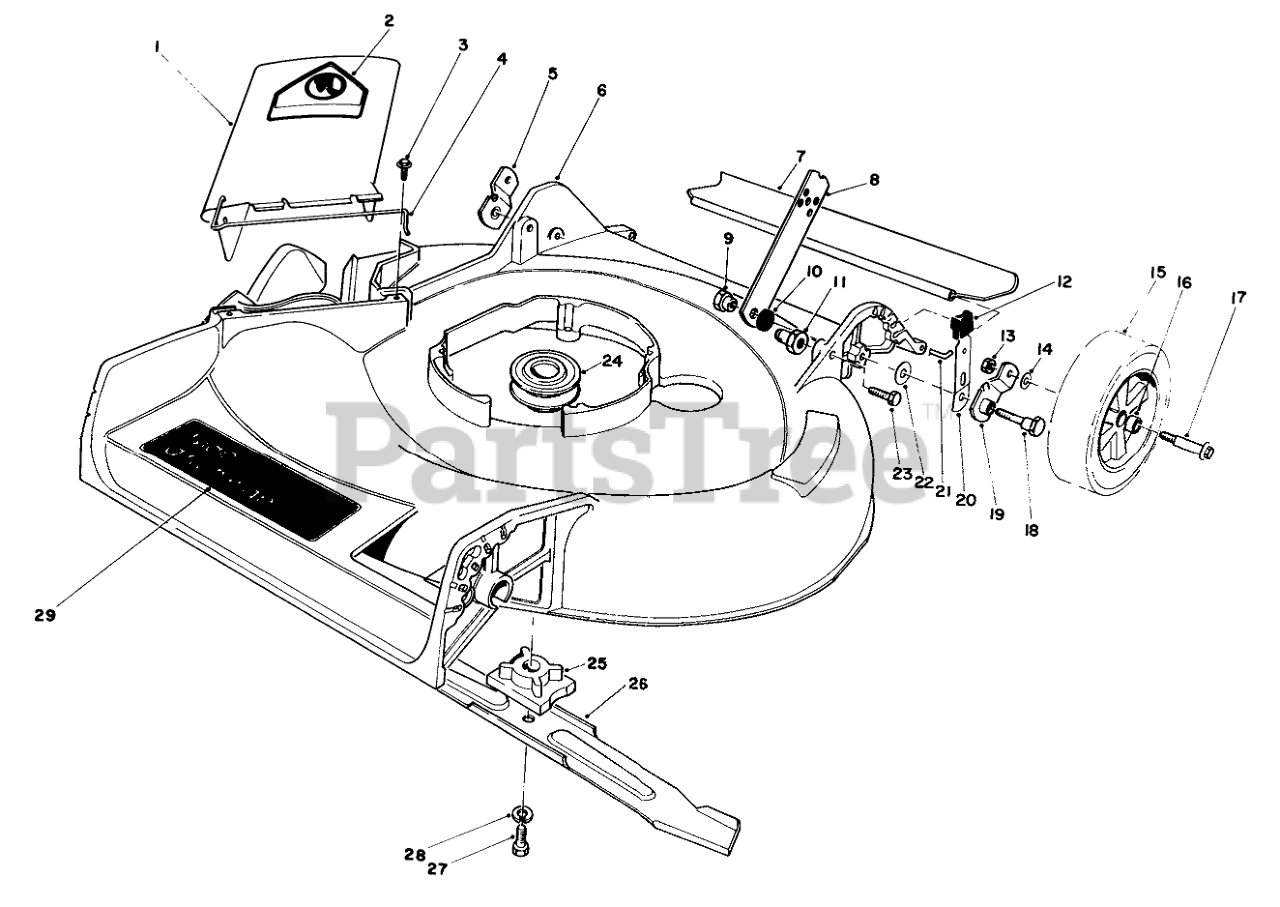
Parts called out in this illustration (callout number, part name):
1	Deflector Assembly (Incl. Ref. #2 & 4)
2	DECAL-DANGER
3	SCREW-HWH
4	SPRING HINGE
5	Pivot Arm
6	Housing
7	REAR SAFETY SHIELD 21
8	HANDLE LATCH
9	HANDLE PIVOT NUT
10	SPACER
11	HANDLE PIVOT NUT
12	KNOB-ARM
13	NUT-LOCK
14	WASHER
15	Wheel & Tire Assembly (Inc. Ref. #16)
16	BUSHING
17	WHEEL BOLT
18	PIVOT SCREW
19	Pivot Arm
20	SPRING ARM ASM
21	SHIELD ROD
22	WASHER-PIVOT
23	SCREW-HH
24	Pulley
25	BLADE RETAINER
26	Blade
27	SCREW-HH
28	WASHER-LOCK
29	Decal-Side Discharge
